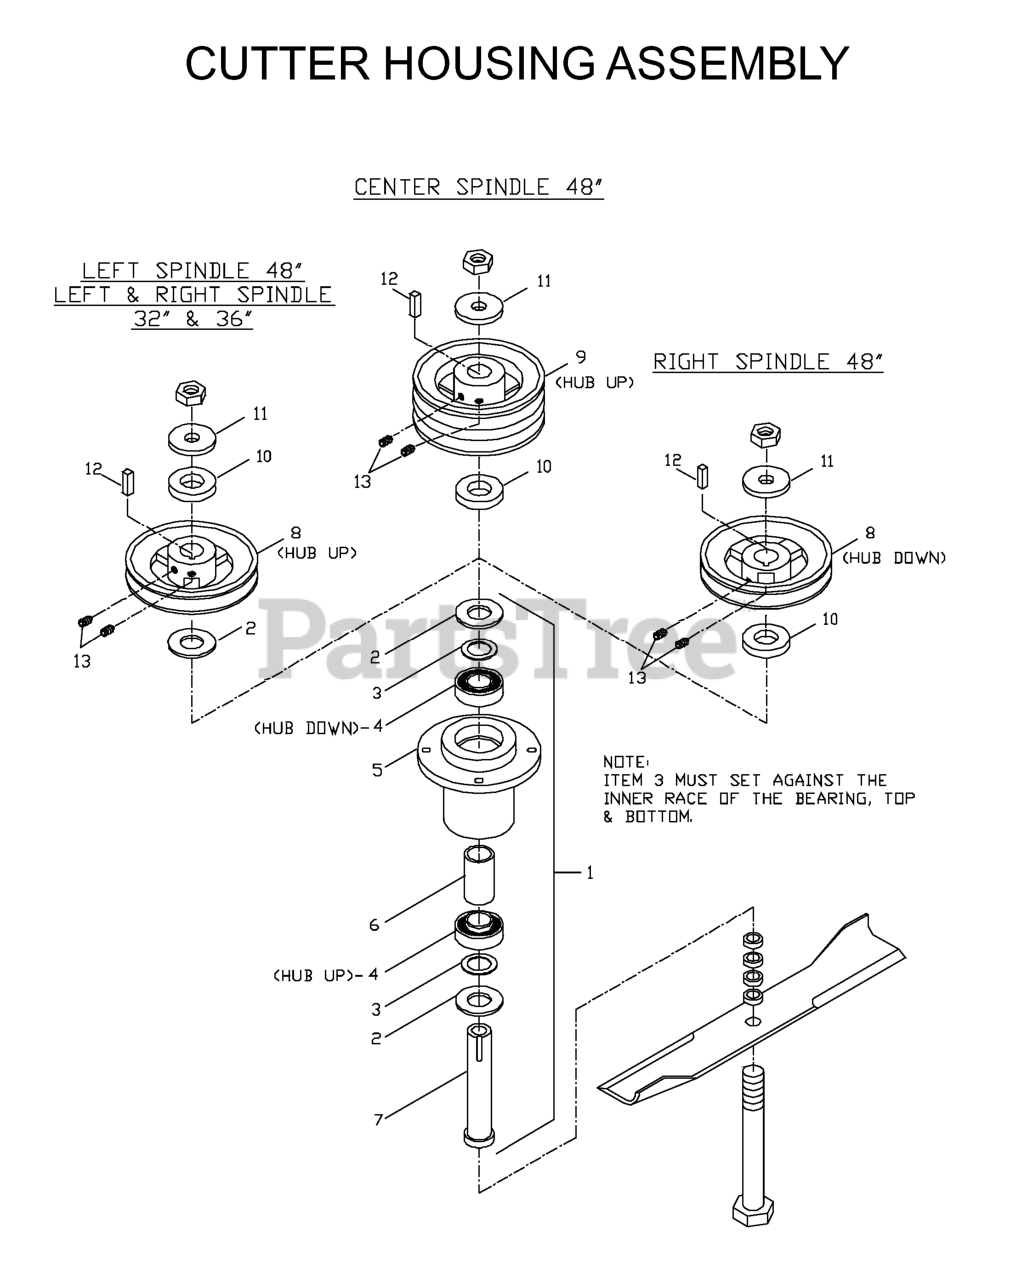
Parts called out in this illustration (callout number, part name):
1	HOUSING ASSEMBLY
2	MACHINERY BUSHING 10 GA.
3	BUSHING.MACHINE.18.GAUGE
4	BEARING
7	SPINDLE SHAFT
8	PULLEY W/SETSCREWS
9	PULLEY, DOUBLE W/SETS
11	WASHER, SUPPORT
12	KEY 1/4 SQ X 1 1/8
13	SET SCREW 5/16 NYLOC
